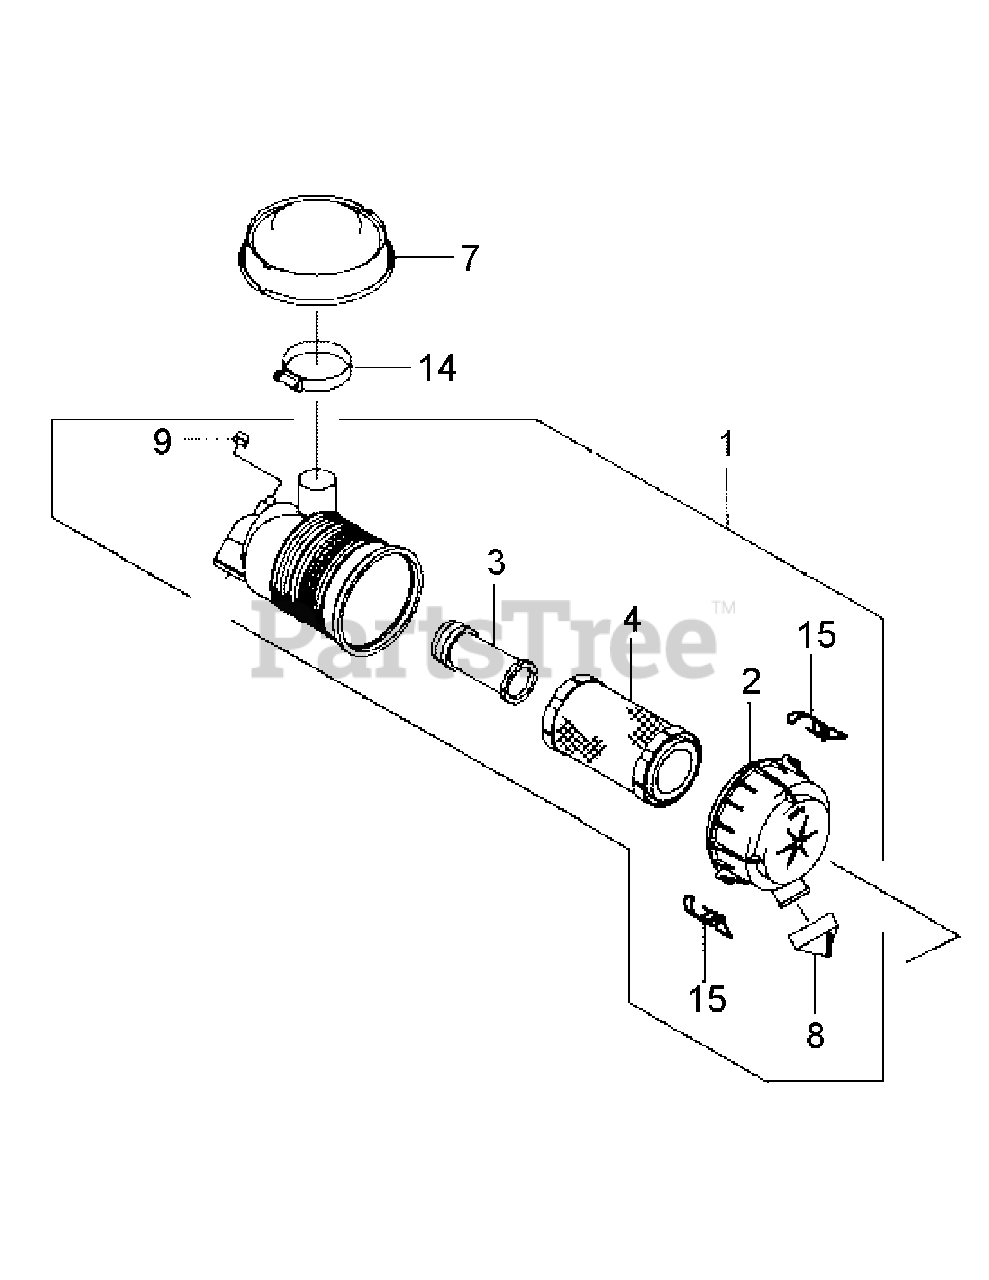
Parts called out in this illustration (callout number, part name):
1	AIR FILTER ASSY.
2	AIR FILTER CASE
3	AIR FILTER ELEMENT
4	PRE FILTER ELEMENT
7	CAP
14	CLAMP
